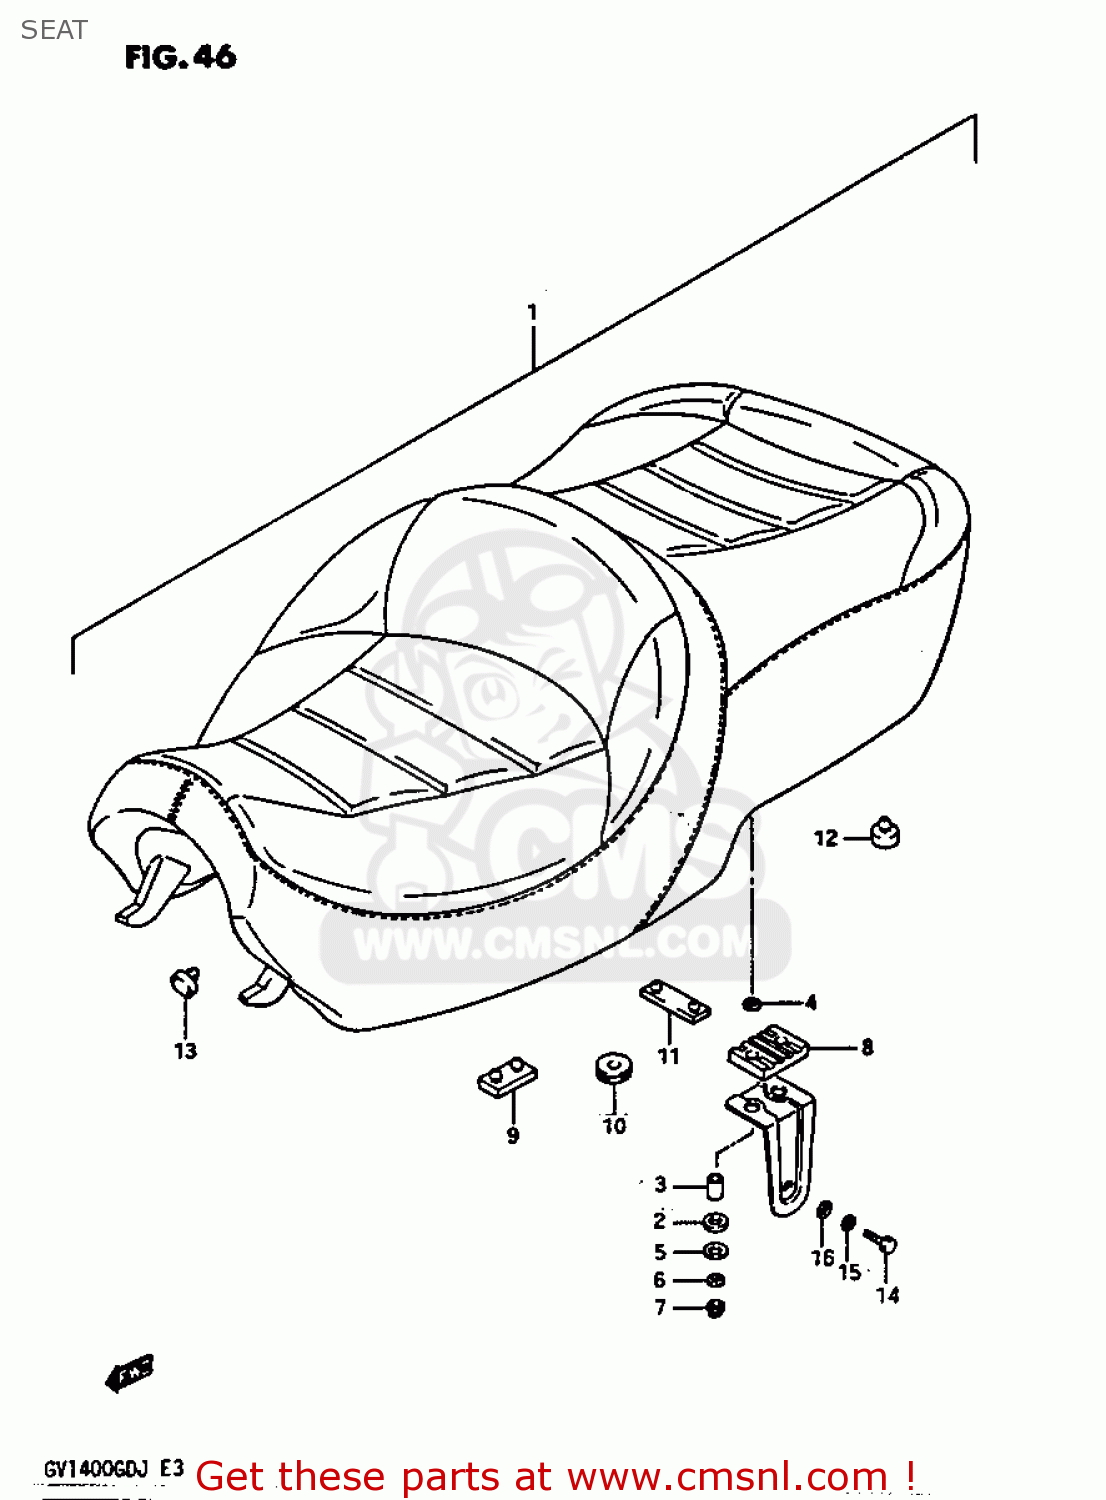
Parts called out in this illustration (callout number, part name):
1	SEAT ASSEMBLY
2	CUSHION,SEAT FR
3	SPACER,SEAT SUPPORT
4	WASHER
5	WASHER
6	WASHER,LOCK
7	NUT
8	CUSHION,FR PLATE
9	CUSHION,SEAT(40X20X15)
10	CUSHION
11	CUSHION
12	CUSHION
13	CUSHION
14	BOLT
15	WASHER,LOCK,8.
16	WASHER
